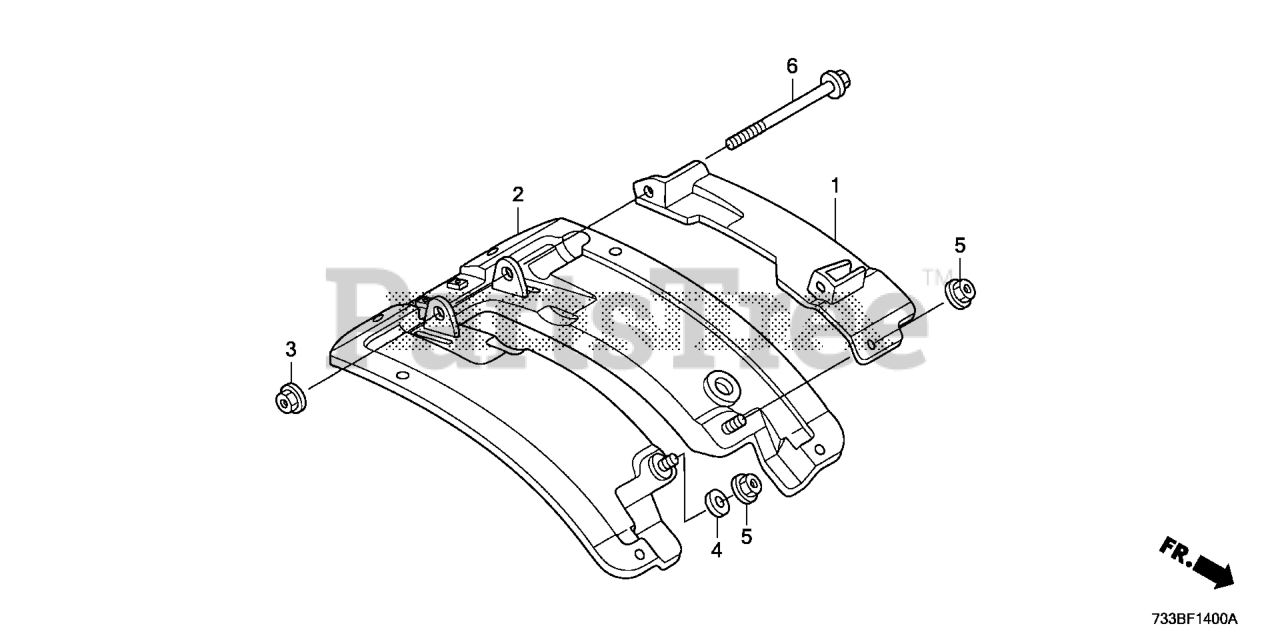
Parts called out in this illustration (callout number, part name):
1	PLATE, REINFORCE
2	FENDER, MAIN
3	NUT, FLANGE (10MM)
4	WASHER (9X22X4.5)
5	NUT, FLANGE (8MM)
6	BOLT, FLANGE (10X95)
